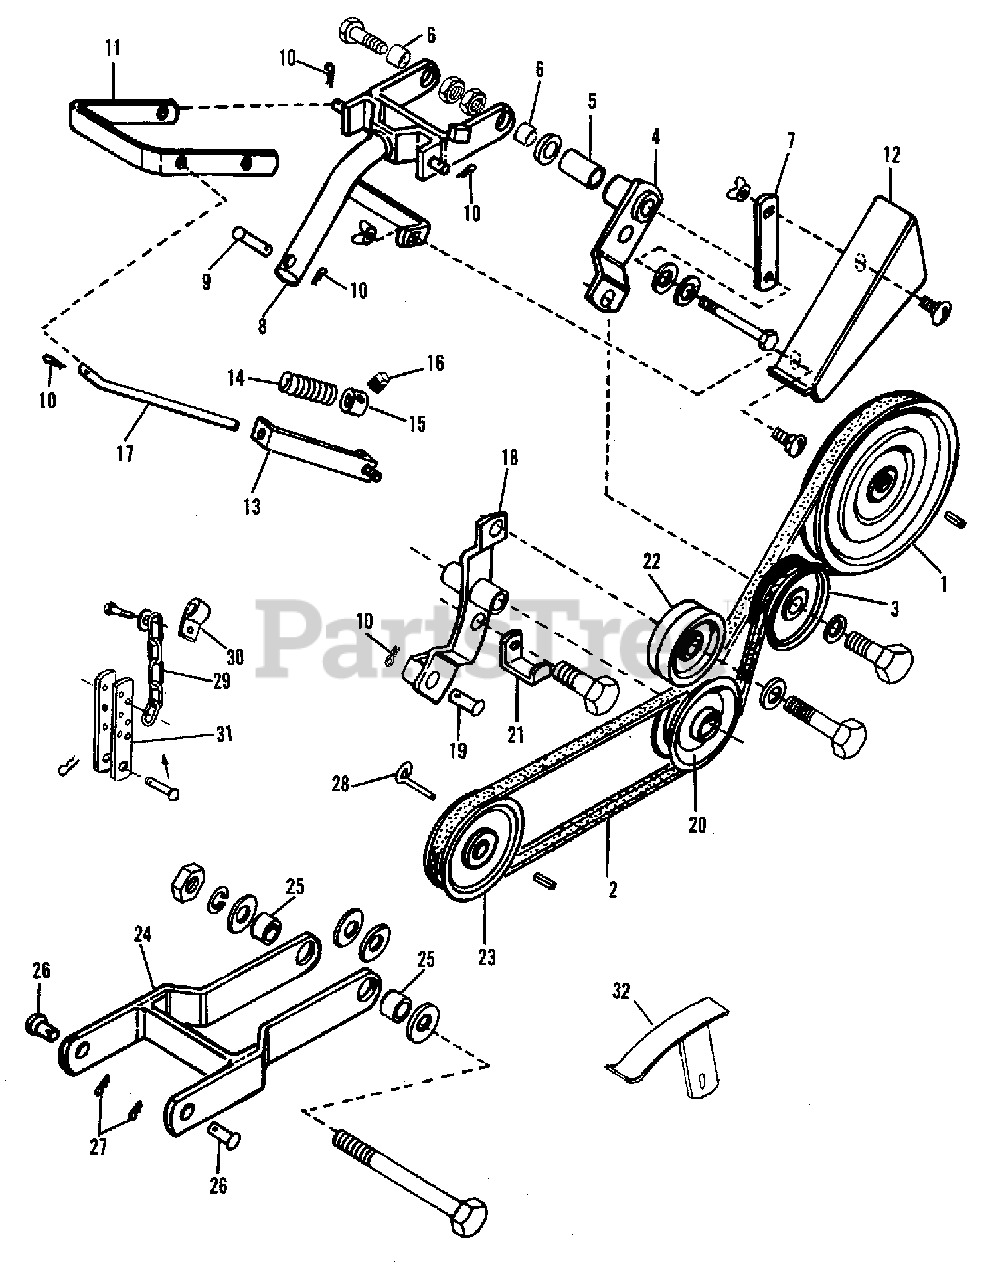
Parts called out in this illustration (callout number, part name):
2	V" BELT`1
3	WASHER, Plain, 5/16
3	CAPSCREW, Hexagon, 3/8NC x 1-1/4
3	WASHER, 3/8, Lock
3	NUT, Hexagon, 3/8NC
4	LEVER ASSEMBLY, Clutch
7	GUARD, Belt, Rear Support
8	BAR ASSEMBLY, Lift
8	WASHER, 3/8
8	WASHER, 7/16
8	CAPSCREW, Hexagon GR5, 7/16NC x 3-1/2
8	LOCKNUT, 7/16
8	CAPSCREW, 7/16NC x 1-1/4, GR5
10	CLIP, Spring
11	HANDLE, Clutch
12	GUARD, Belt
12	BOLT, 5/16NC x 1/2
12	NUT, Lock, 5/16NC
13	GUIDE ASSEMBLY, Rod
13	NUT, Lock, 5/16NC
15	COLLAR, Set
16	SETSCREW, Square Head, 1/4NC x 3/8
17	ROD, Clutch
18	IDLER ASSEMBLY, Arm
18	CAPSCREW, 3/8NC x 7/8
18	NUT, Full, 3/8NC
18	WASHER, Lock, 3/8
18	WASHER, Plain, 5/16
18	CAPSCREW, 3/8NC x 1-1/4
20	PULLEY, Idler
21	GUARD, 1/8 x 1 x 4-1/8
22	PULLEY, Idler
24	FRAM ASSEMBLY
24	CAPSCREW, 3/8NC x 1
24	WASHER 3/8, Plain
24	LOCKWASHER, 3/8
24	NUT, 3/8NC
28	STOP, Belt
30	CLIP, Chain
31	BRACKET ASSEMBLY, Depth Limit
31	PIN, Quick
31	PIN, Round head
32	GUARD, Belt
32	CAPSCREW, 3/8NC x 1-3/4
32	WASHER, 3/8, Plain
